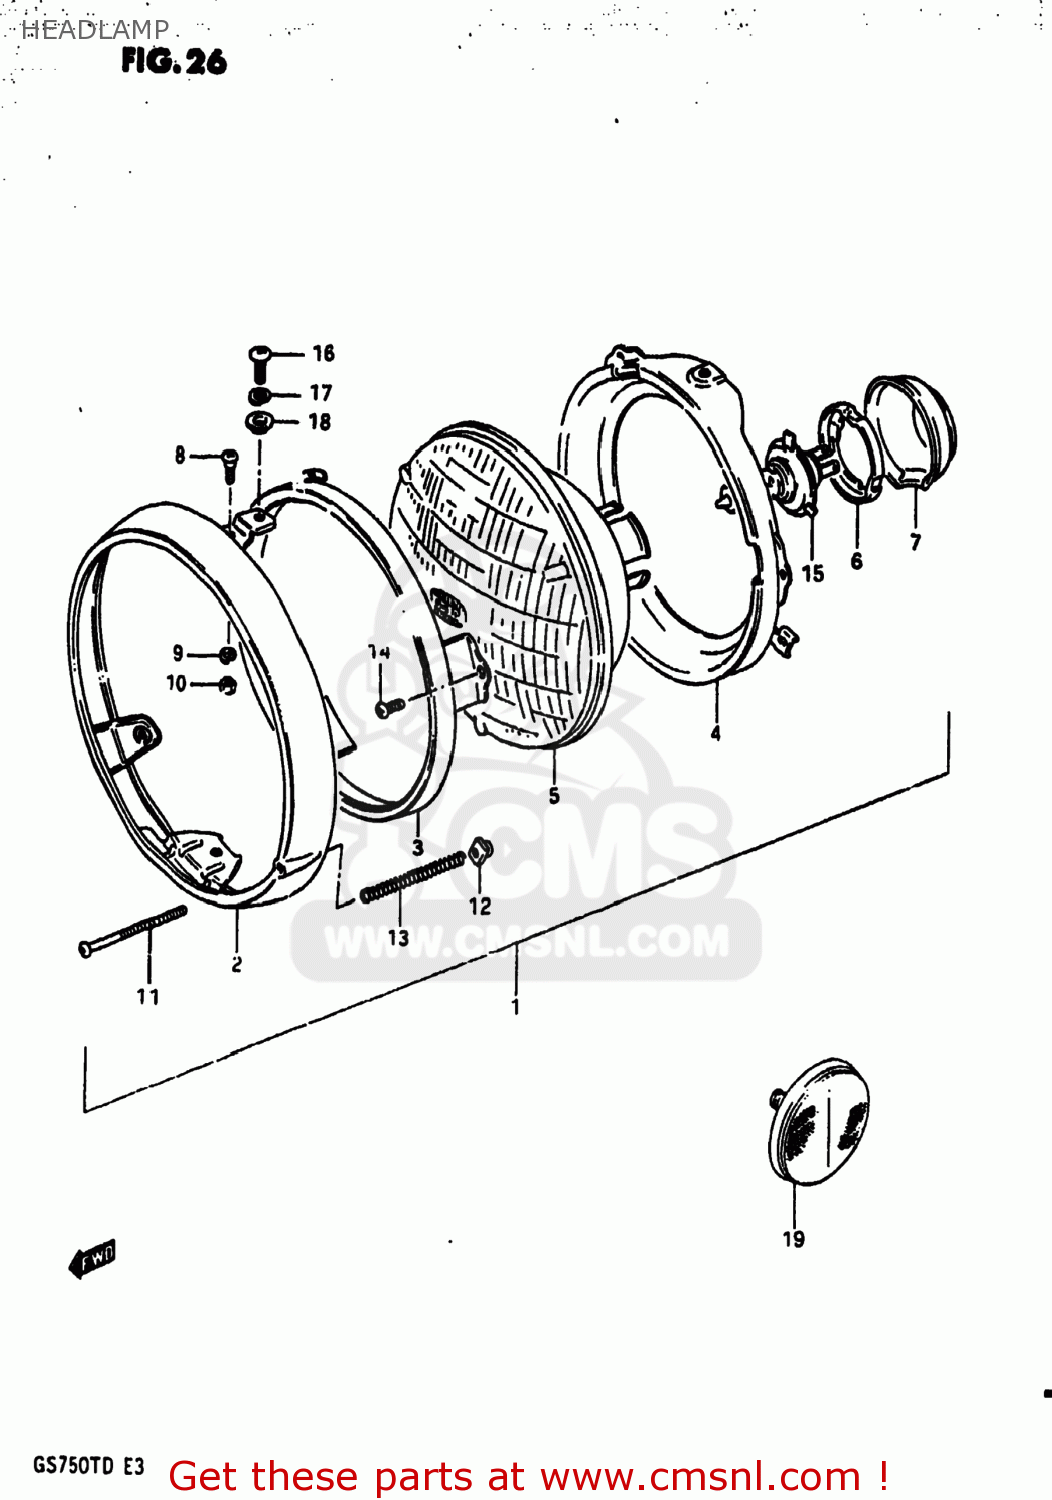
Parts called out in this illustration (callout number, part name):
1	HEADLAMP ASSEMBLY
2	RIM
3	RETAINING RING
4	RING
5	LAMP UNIT
6	SETTING,BULB
7	COVER,HEADLAMP SOCKET
8	H/LAMP LENS UNIT FITING SCRE
9	LOCK WASHER
10	NUT
11	SCREW,HEADLAMP ADJUST
12	NUT
13	SPRING,ADJUSTING
14	SCREW
15	BULB(12V60/55W,H4)
16	SCREW
17	WASHER,LOCK
18	WASHER
19	REFLEX REFLECTOR,RR
